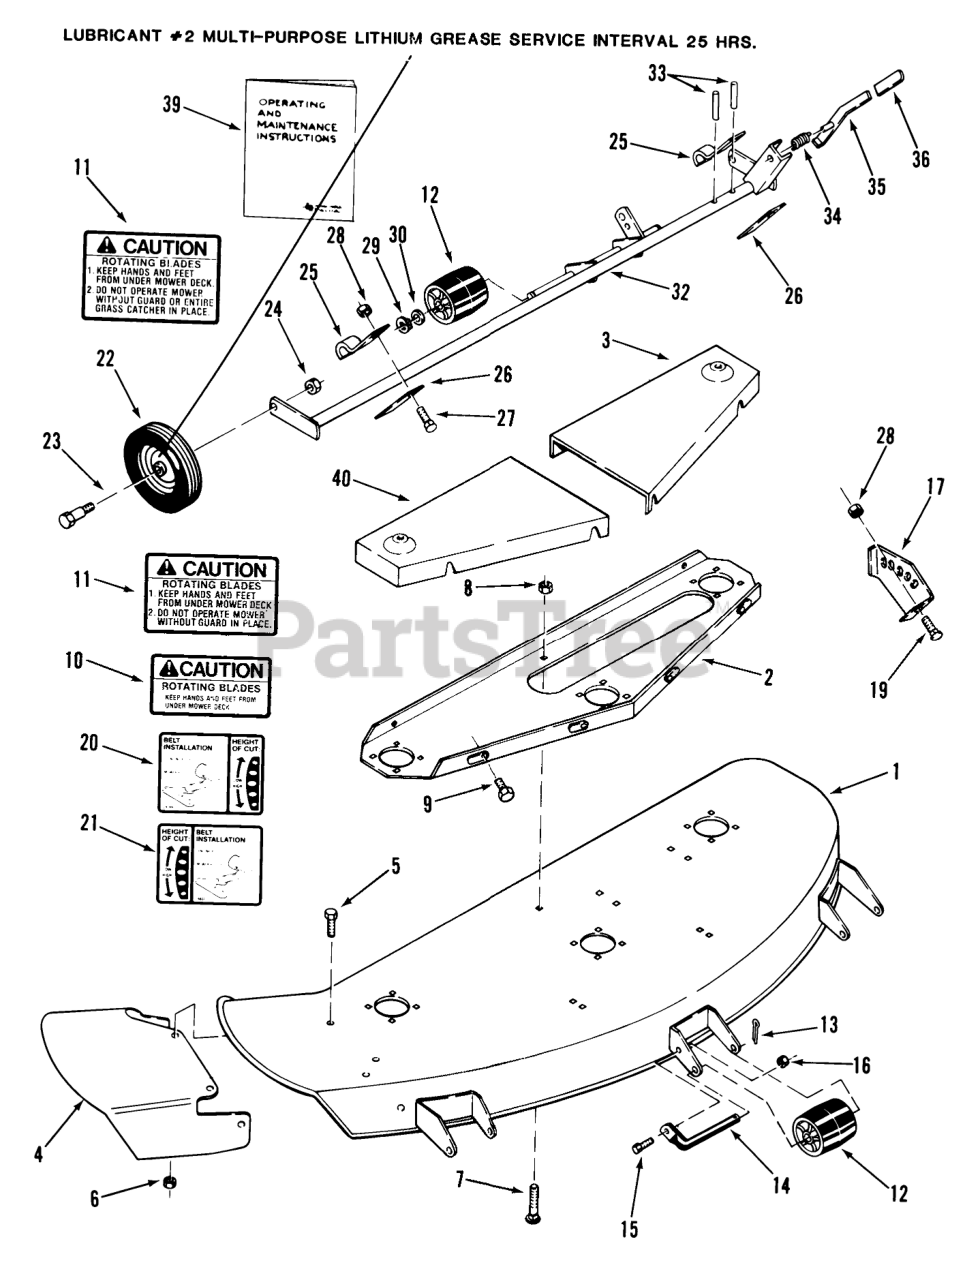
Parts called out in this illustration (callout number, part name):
1	ASSY-48 MOWER DEC R
1	ASSY DECK 42"MOWE R
2	Channel
3	Belt Cover LH
4	Chute Extension
5	Bolt
6	Nut
7	Bolt-Carriage
8	NUT
9	Screw
9	SCREW -4
10	Caution Decal
11	Decal-Caution
11	DECAL
12	Roller
13	Cotter Pin
14	ROLLER-SHAFT
15	H H C S
16	Nut
17	LH QUADRANT R
17	Quadrant
19	Bolt
20	DECAL-HEIGHT & BELT
21	DECAL-HEIGHT & BELT
22	WHEEL
23	BOLT-SHOULDER
24	Nut
25	Clamp
26	Bar
27	Bolt
28	NUT
29	Retaining Ring
30	Washer
32	ASSY-GAGE WHEEL S R
32	Gage Wheel Support
33	PIN-SPIROL
34	SPRING-COMPRESSION
35	Lever
35	LEVER ASSY R
39	Operating and Maintenance Instructions
40	Belt Cover RH
